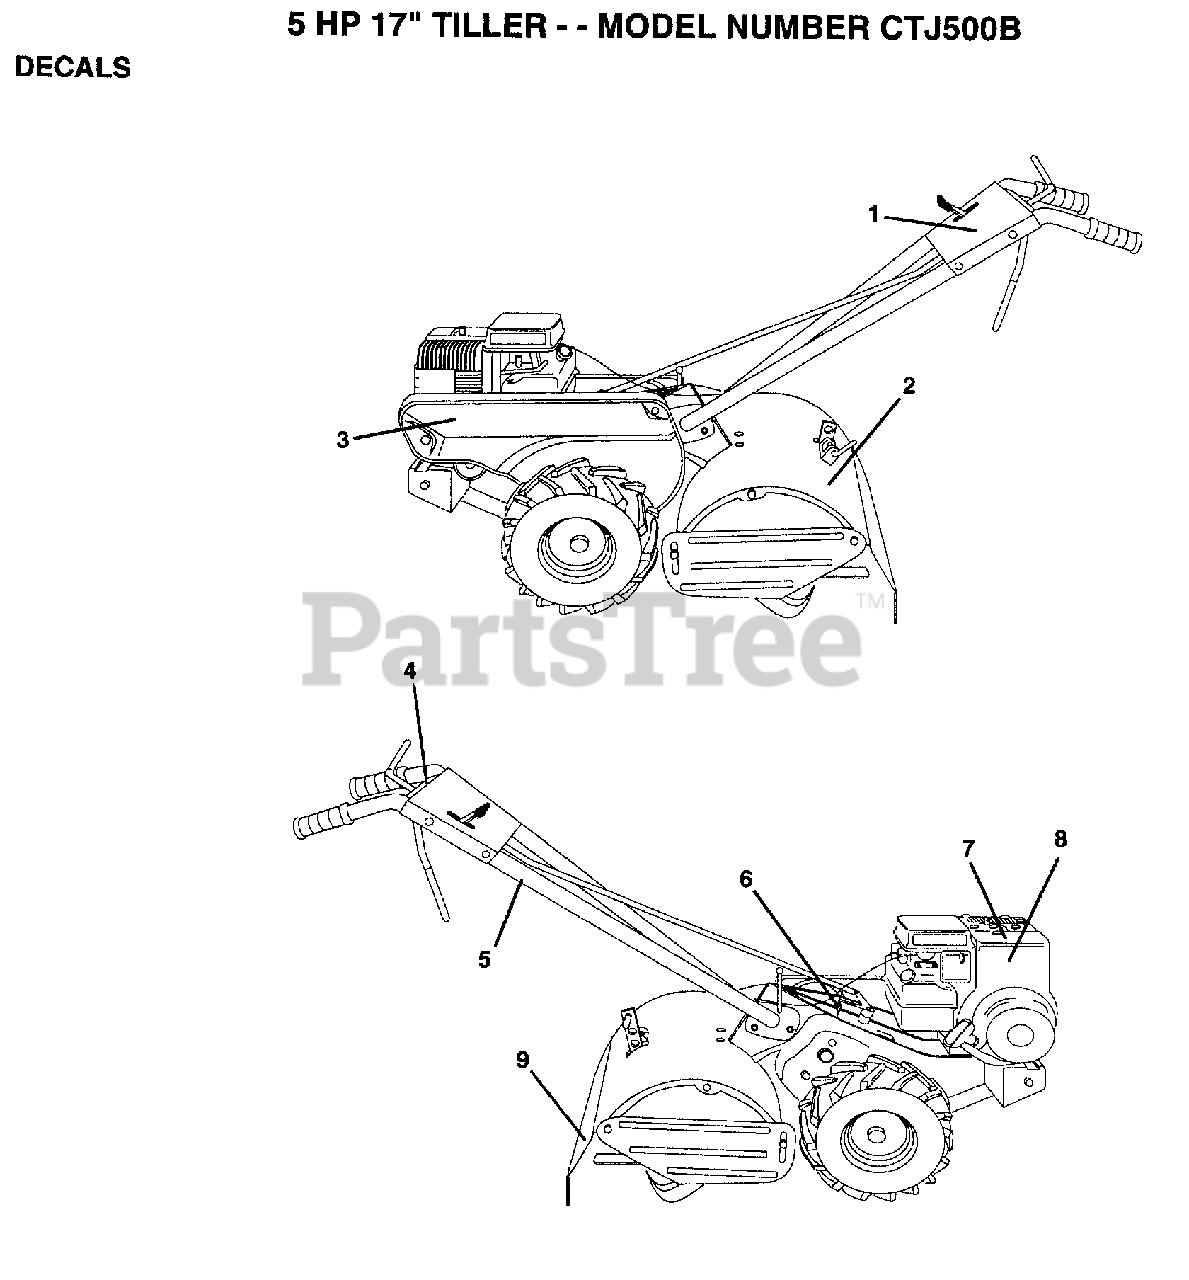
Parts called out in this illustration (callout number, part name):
1	DECAL.CTL.PANEL
3	DECAL.GUARD.BELT
5	DECAL TI
6	DECAL CRT
9	DECAL TI
